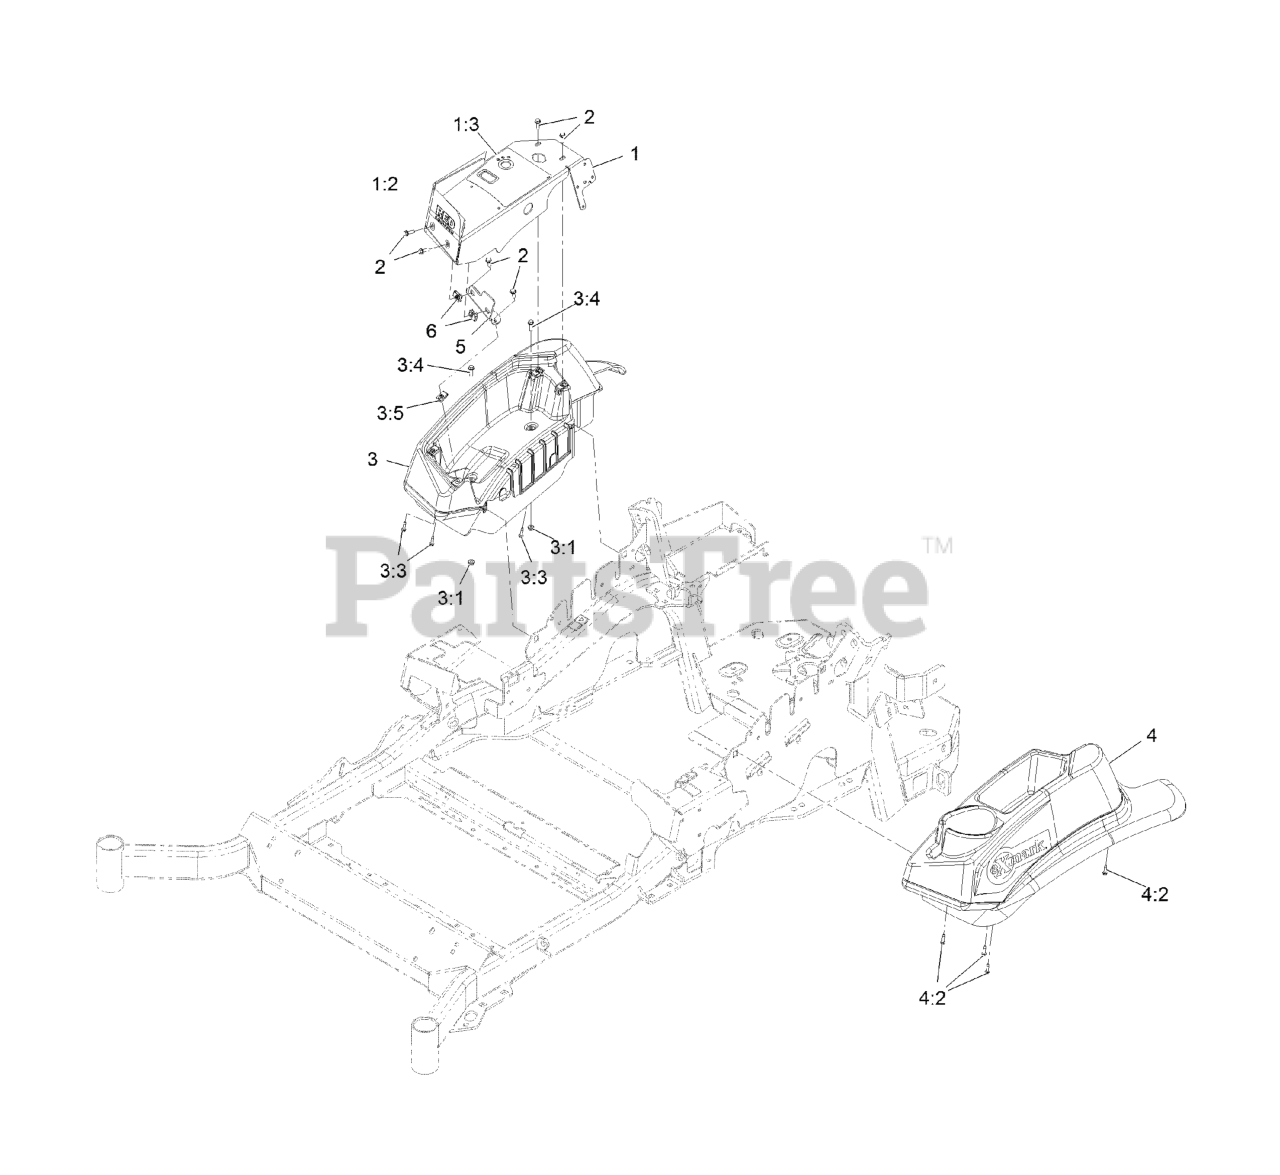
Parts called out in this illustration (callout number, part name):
1	COVER PANEL ASM W/DECALS
1:2	DECAL-CONTROL PANEL RED
1:3	DECAL-CONSOLE
2	SCREW-HWH
3	CONSOLE,RH NARROW ASM
3:3	SCREW,THD FORM,HWH
3:4	SCREW-HWH
4	CONSOLE.LH NARROW ASM
4:2	SCREW,THD FORM,HWH
5	BRACKET-CONSOLE
